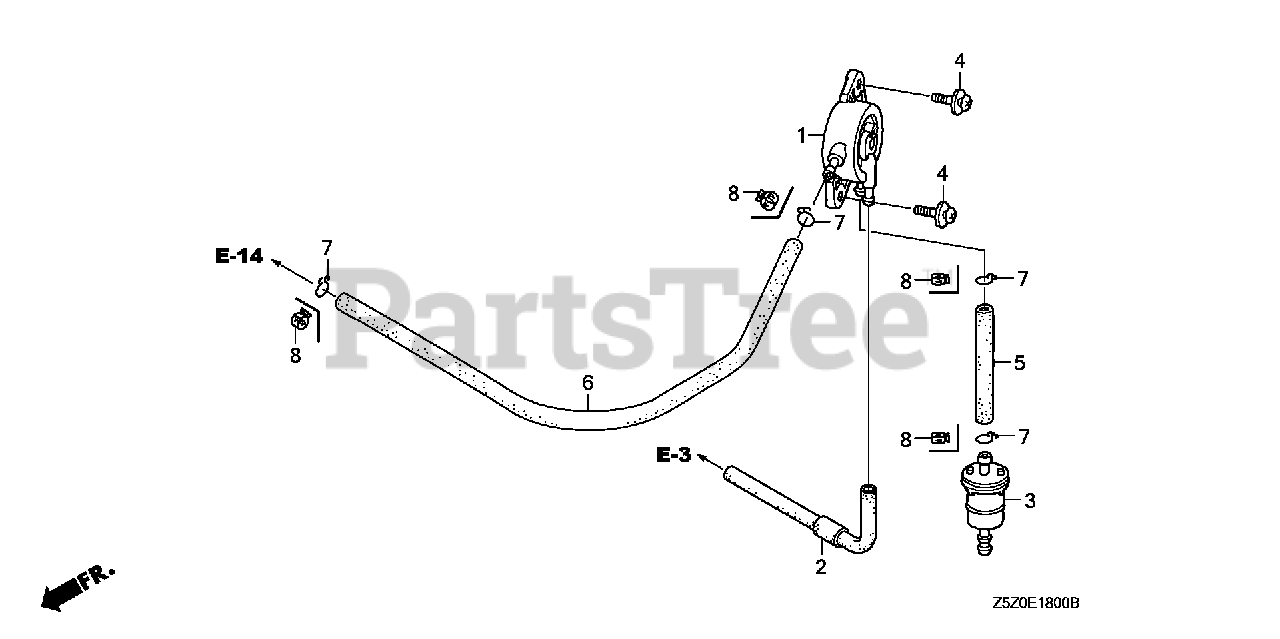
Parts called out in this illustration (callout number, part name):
1	PUMP ASSY., FUEL
2	TUBE, DIAPHRAGM
3	FILTER, FUEL
3	STRAINER, FUEL
4	SCREW-WASHER (5X16)
5	TUBE, FUEL (5.3X100) (FKM)
5	BULK HOSE, FUEL (5.5X3000) (Honda Code 5338587). (5.5X150)
6	TUBE, FUEL (5.3X350) (FKM)
6	BULK HOSE, FUEL (5.5X3000) (Honda Code 5338587). (5.5X150)
7	CLIP, TUBE (B10)
8	CLAMP, TUBE (D10)
